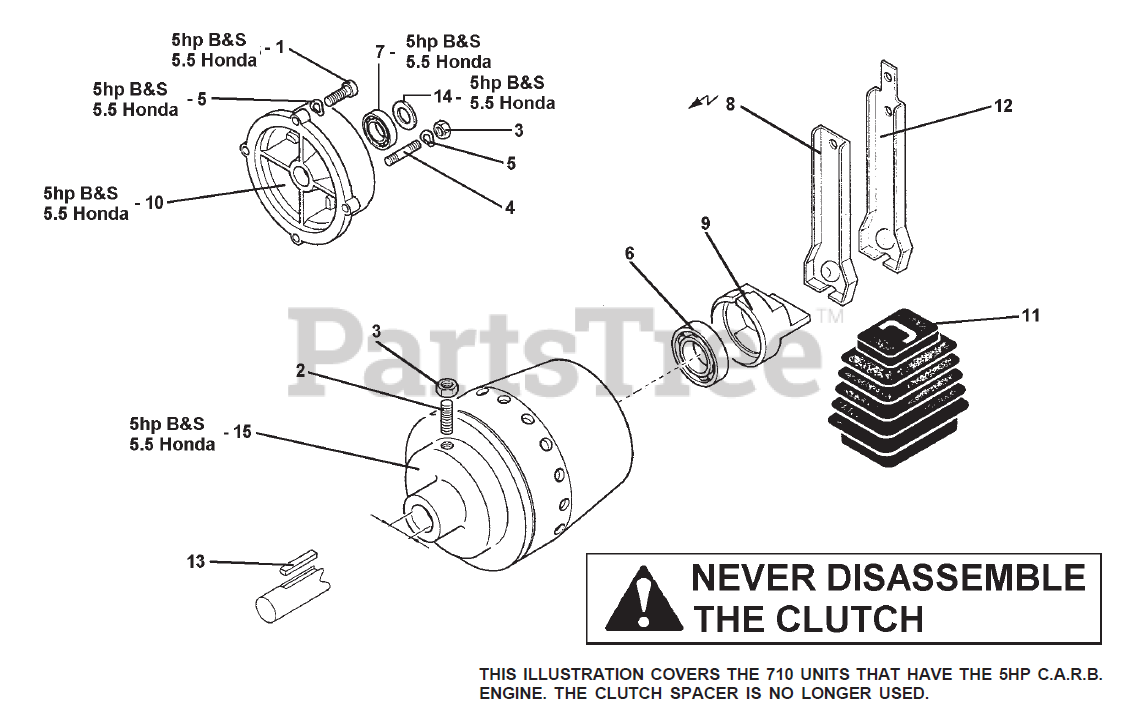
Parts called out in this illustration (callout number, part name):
1	SCREW 5/16X7/8"
2	SCREW M8X30
4	STUD, M8X40X14X14
5	WASHER, WAVE
6	BEARING, M17X40X12
7	BEARING, 20X47X14
8	CLUTCH LEVER, ELECTRIC START
9	CONE PUSHER
10	FLANGE, 5HP B&S ENGINE
12	LEVER, RECOIL START
14	WASHER, 5HP B&S
15	CLUTCH, 5HP B&S
